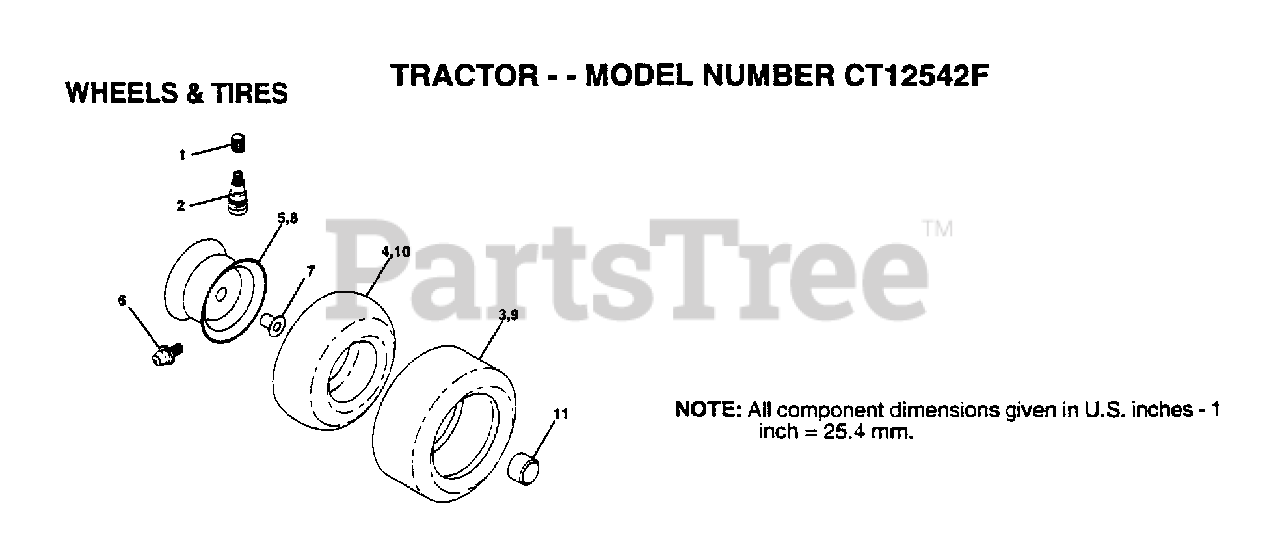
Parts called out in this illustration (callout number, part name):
1	VALVE CAP
2	VALVE STEM LT
4	TUBE.5.3/4.5/6
5	"RIM.ASM.6""FRONT"
6	FITTING LT
7	"FLANGE, BEARING"
8	"RIM.ASM.8""REAR"
10	TUBE.18X9.5-8
11	HUB CAP
